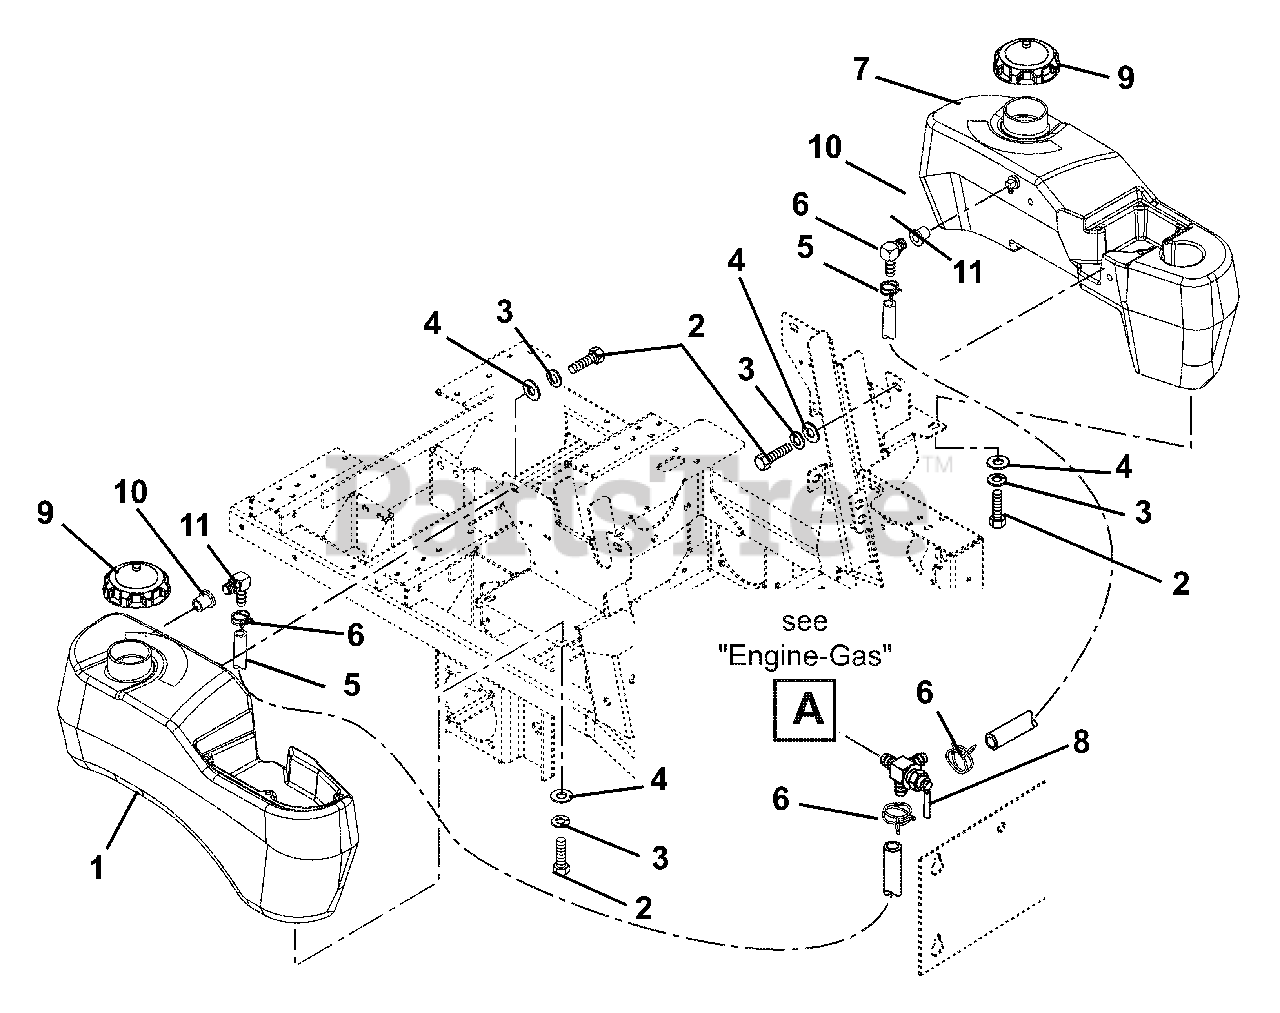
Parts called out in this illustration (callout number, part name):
1	Tank, Gas Fuel-Right Hand
2	Bolt, Hex .31-18 x .75 Grade 5
3	Washer, Locking .31 x .078
4	Washer, Flat Steel .38 x .875 x .083
5	Gas Line-Bulk .25 I.D.
6	Clamp, Hose Wire .49/.51 x .116
7	Tank, Left Hand Fuel (EYE-Q) 200 Series
8	Valve, Fuel
9	Cap, Gas
11	Fitting, Tank
